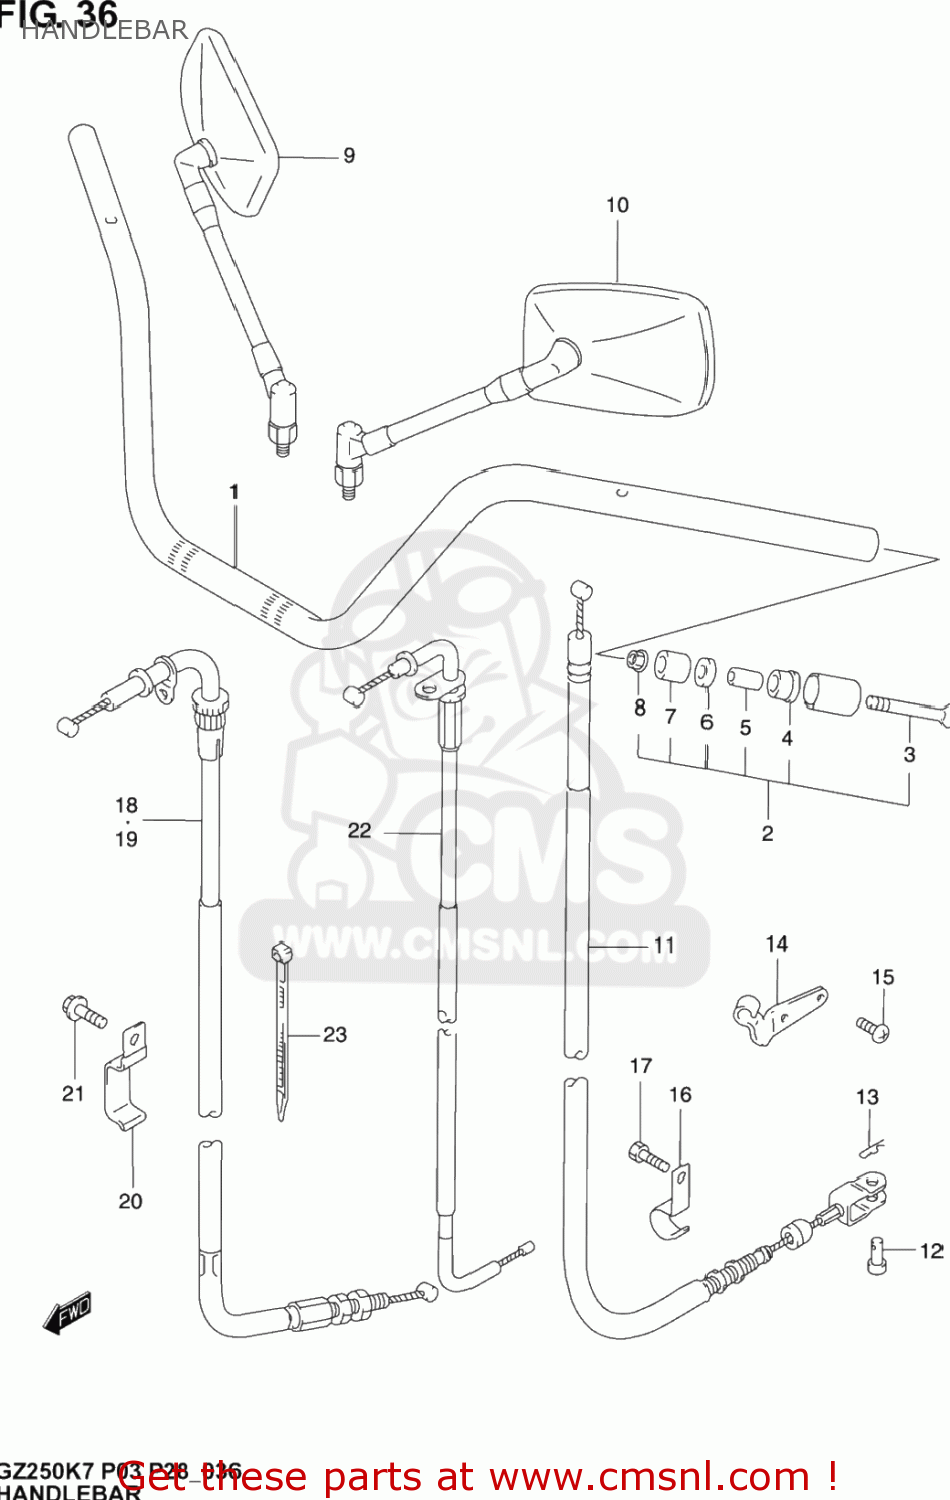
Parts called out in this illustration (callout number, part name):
1	HANDLEBAR
2	BALANCER SET,HANDLEBAR
3	SCREW(6X125)
4	EXPANDER,HANDLE BALANCER NO.2
5	SPACER,EXPANDER
6	WASHER(6.5X14X2)
7	EXPANDER,HANDLE BALANCER
8	NUT
9	REARVIEW MIRRO
10	REARVIEW MIRRO
11	CABLE ASSY,CLUTCH
12	PIN(L:13)
13	PIN
14	STOPPER,CLUTCH CABLE
15	BOLT
16	CLAMP,CLUTCH CABLE NO.1
17	SCREW
18	CABLE ASSY,THROTTLE NO.1
19	CABLE ASSY,THROTTLE NO.2
20	CLAMP
21	BOLT
22	CABLE,STARTER
23	CLAMP(L:95)
